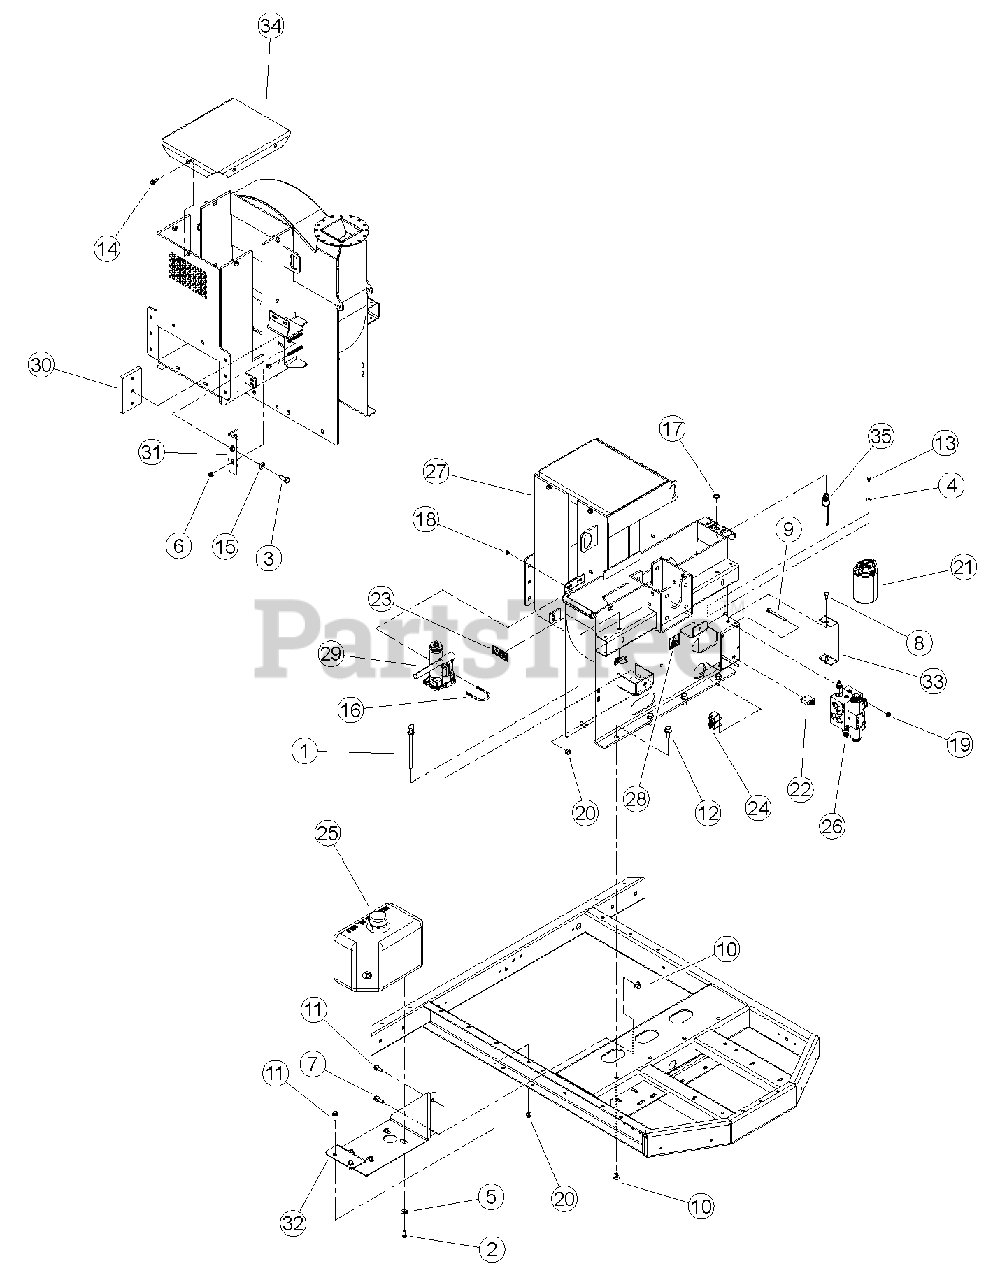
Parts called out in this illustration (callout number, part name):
1	PIN, HITCH 1/2 X 6-1/2 W/ LYNCH
2	BOLT, 3/8 X 3/4 GR5 HEX CAPSCREW ZP
3	BOLT, 1/2 X 1-1/4" GR5 HHCS NC ZP
4	WASHER, 1/4" FLAT ZP
5	WASHER, 3/8" FLAT ZP
6	NUT, 3/8" SERRATED FLANGE NC ZP
7	BOLT, 3/8 X 1-1/4 FLANGE NC
8	BOLT, 5/16 X 3/4 FLANGE NC
9	BOLT, 5/16 X 3-1/2 SERRATED FLANGE NC
10	NUT, 1/2-13 NYLOCK FLANGE
11	BOLT, 3/8 X 1 FLANGE NC
12	BOLT, 1/2 -13 X 1-1/4 FLANGE NC
13	BOLT, 1/4 X 5/8" HHCS GR5 ZP
14	BOLT, 3/8 X 3/4" SERRATED FLANGE
15	WASHER, 1/2 HI-STRENGTH SAE ZP
16	U-BOLT, 1/4 X 1-1/2 PIPE
17	NUT, 5/8-32 JAM
18	NUT, 1/4-20 NYLOCK-FLANGE
19	NUT, 5/16-18 NYLOCK-FLANGE
20	NUT, 3/8-16 NYLOCK FLANGE
21	ASSEMBLY, HYDRAULIC FILTER
22	CIRCUIT BREAKER, 10 AMP RESETTABLE
23	DECAL, CRUSHING ISO
24	RELAY, 12V SPDT W/ FLANGE
25	TANK, HYDRAULIC
26	ASSEMBLY, HYDRAULIC FEED FLOW VALVE W/ PS
27	ASSEMBLY, 6" CHIPPER HOUSING WITH DECALS
28	DECAL, SHIELD DANGER ISO
29	JACK, HYDRAULIC 2 TON
30	ANVIL, 6" CHIPPER
31	WELDMENT, BLOCK ADJUSTOR
32	BRACKET, HYDRAULIC TANK
33	COVER, CHIPPER SHAFT
34	WELDMENT, TOP ROLLER COVER
35	ASSEMBLY, SEALED SWITCH
